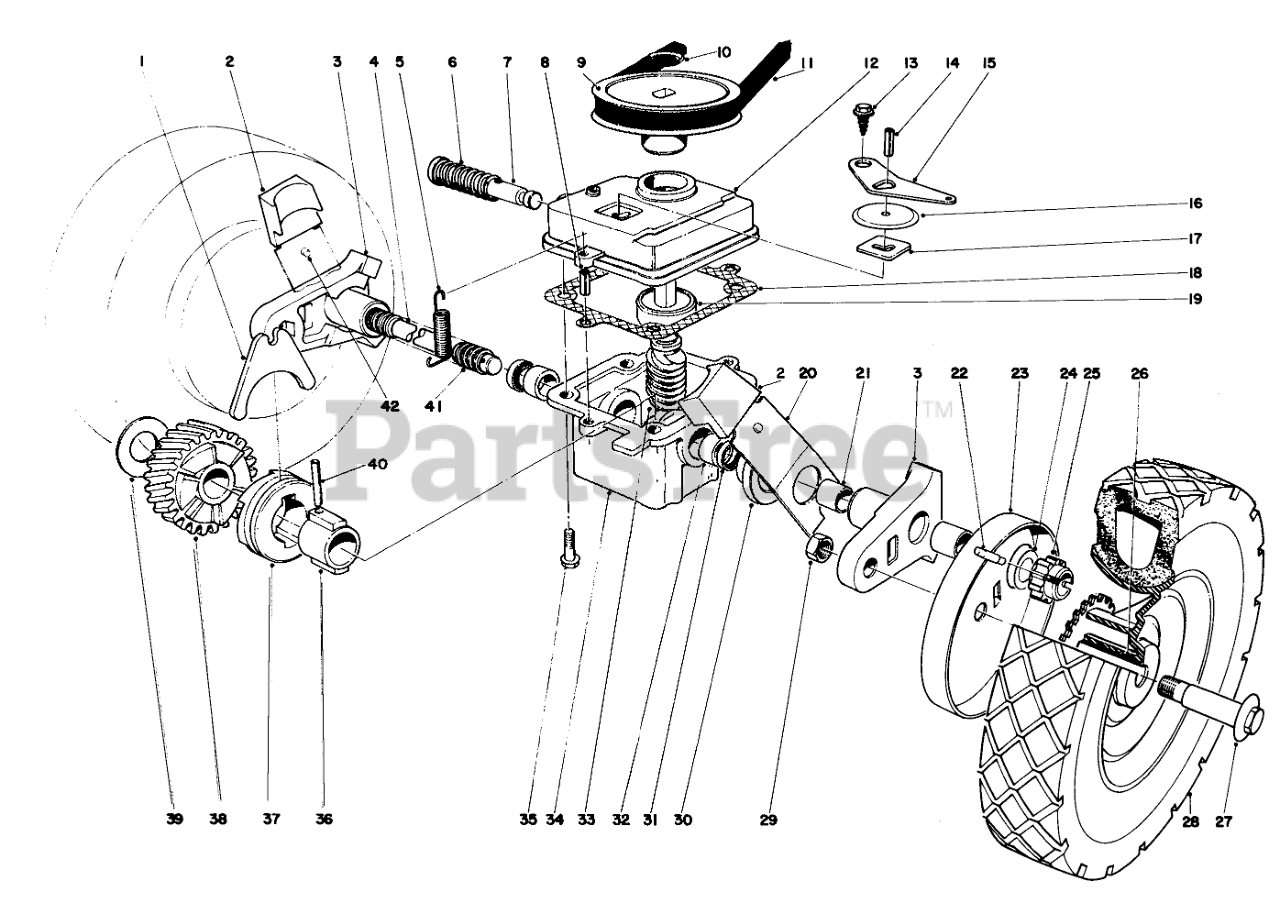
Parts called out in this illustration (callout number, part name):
1	SHIFTER FORK
2	Knob
3	Pivot Arm (Incl. Ref. No. 21)
4	Drive Shaft
5	TENSION SPRING
6	SPRING
7	Shift Rod
8	3/16 X 1/2 ROLL PIN
9	PULLEY
10	PUSH-ON 93-3236
11	V BELT
12	GEAR CASE COVER
13	Screw
14	PIN-ROLL
15	SHIFTER ARM
16	TRANS DUST COVER
17	LATCH PLATE
18	GASKET
19	Bearing
20	LH SPRING ARM ASM
21	BUSHING
22	PIN-GROOVED
23	WHEEL COVER
24	WASHER-THRUST
25	Pinion
26	WHEEL BUSHING
28	Wheel & Tire (Incl. Ref. No. 26)
29	Nut
30	End Cap
31	Seal
32	Bushing
33	WORM SHAFT
34	Gear Case (Incl. Ref. #31 & 32)
35	Screw
36	SLEEVE
37	CLUTCH JAW
39	THRUST WASHER
40	COIL PIN
41	COVER-SHAFT, DRIVE
42	Spring Arm R.H.
